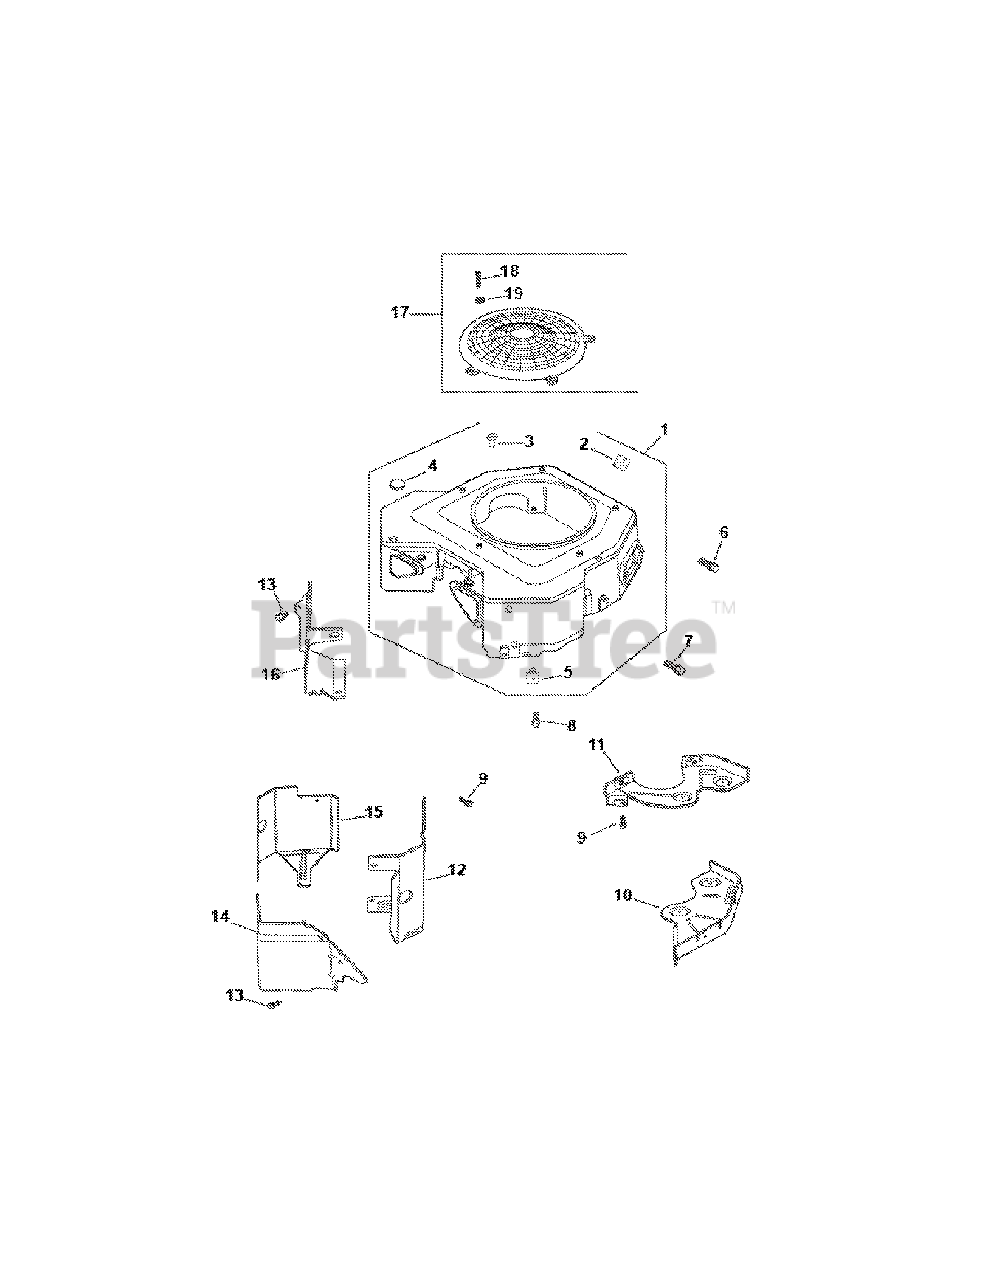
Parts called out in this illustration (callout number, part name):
1	Blower Housing
2	Plastic Nut
3	Tapping Screw
4	9/16" Button Plug
6	Screw
8	Screw
10	Backing Plate # 2
11	Backing Plate # 1
12	Cylinder Barrel Baffle # 2 Side
14	Valley Baffle # 2 Side
15	Cylinder Barrel Baffle # 1 Side
16	Valley Baffle # 1 Side
17	Fixed Guard Kit
18	Pan Head Screw
